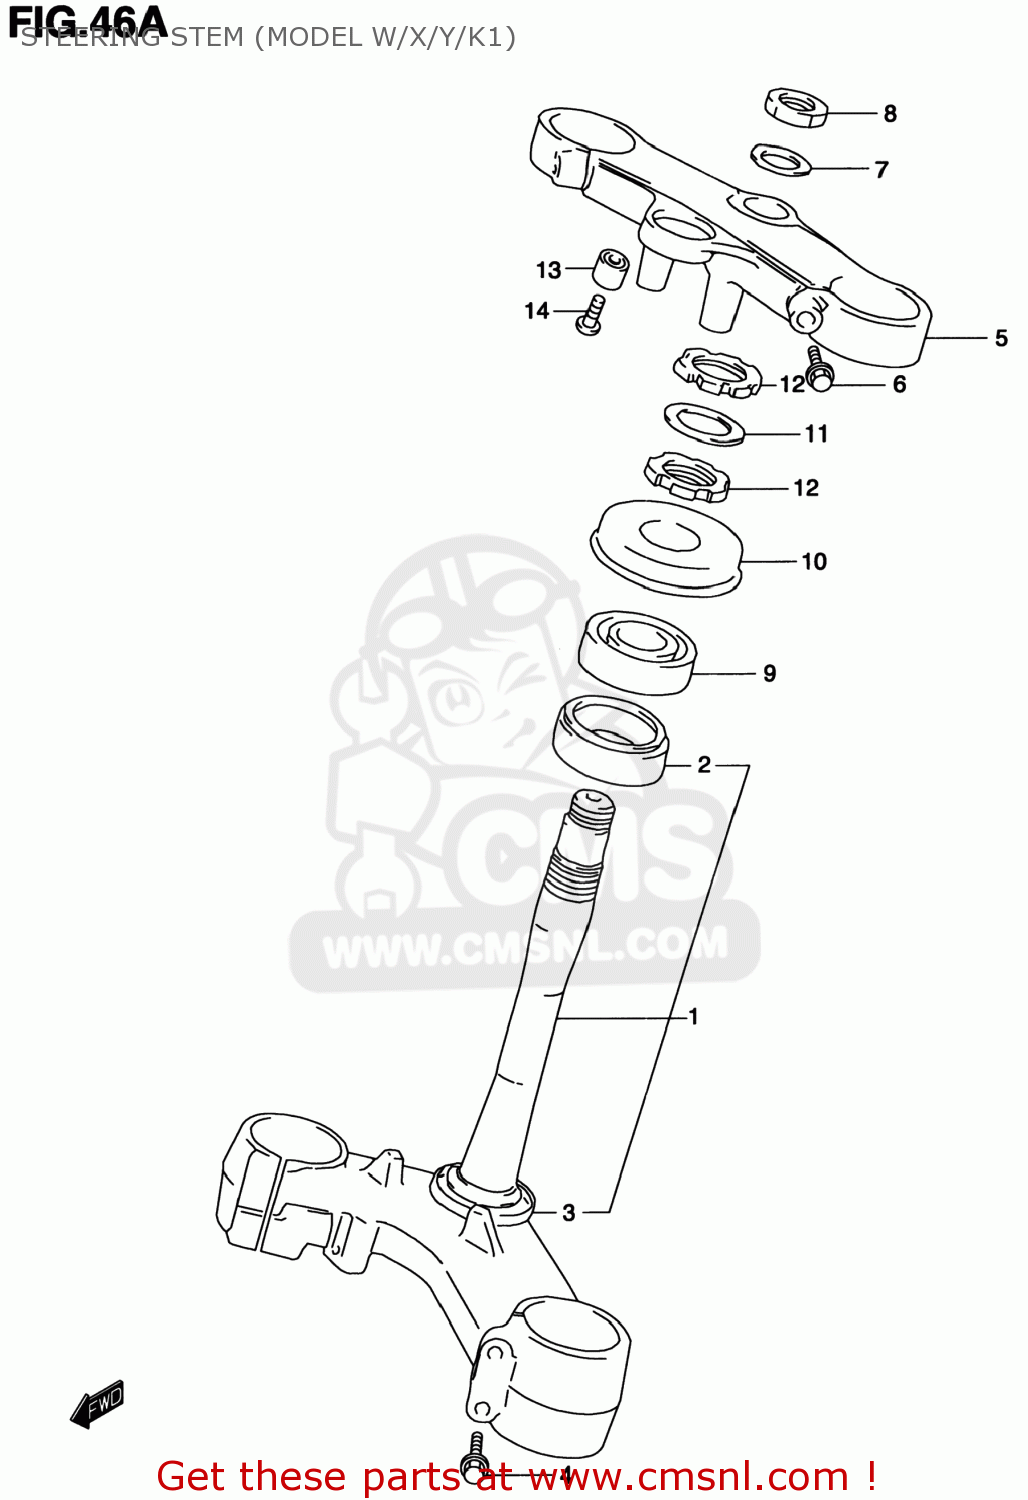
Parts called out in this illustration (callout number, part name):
1	STEM,STEERING
2	BEARING(30X55X17)
3	SEAL,STEERING LWR
4	BOLT
5	HEAD,STEERING STEM
6	BOLT
7	WASHER,STEM HEAD(24.5X34X1.6)
8	NUT
9	BEARING(30X55X17)
10	SEAL,STEERING UPR DUST
11	WASHER,STEERING STEM
12	NUT,STEERING STEM
13	BALANCER,BRACKET UPR
14	SCREW
